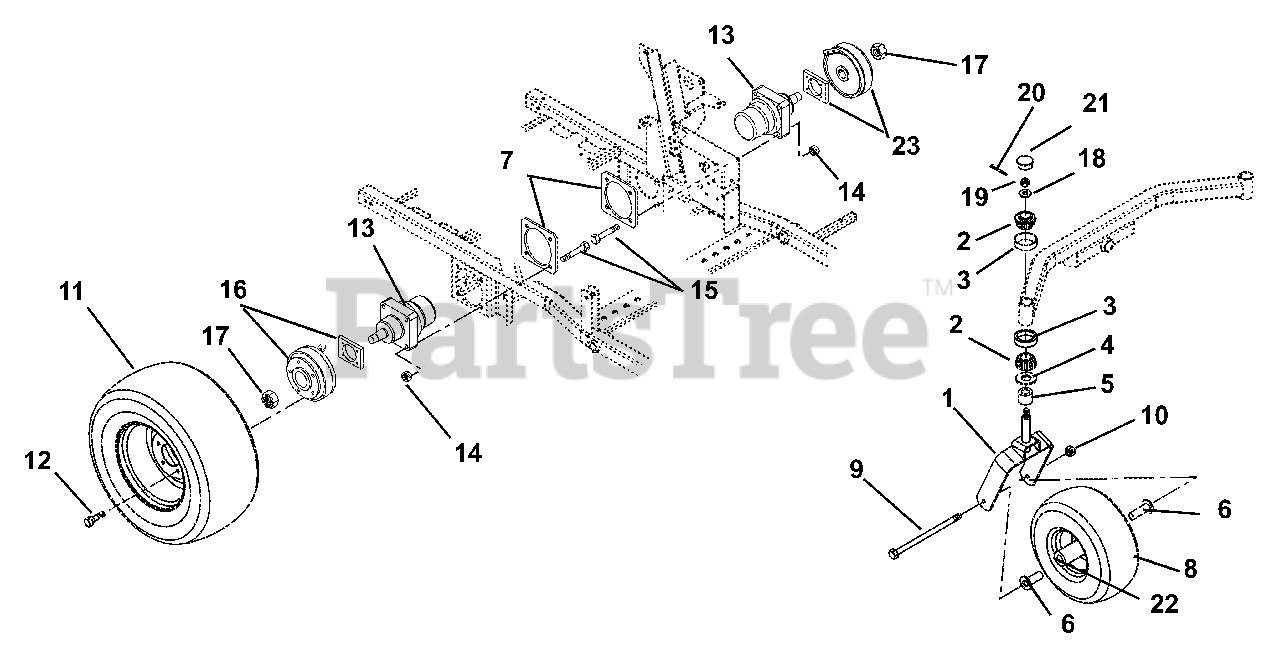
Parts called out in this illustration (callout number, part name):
1	FORK-FRONT
2	BRG, CONE W/ GREASE
3	BRG-CUP1.980X.420
4	BEARING SEAL 1.5 X 2 X .18
5	SPACER 1.005X1.5075X.375
6	SPACER - WHEEL
7	PLATE, MOTOR SUPPORT (BLACK)
8	WHEEL/TIRE ASM
9	@BLT-HEX .50-13X9.00 GR5 YWZC
10	@NUT-LK-CTR .50-13 YWZC
11	TIRE/WHEEL ASSY 24X12-12
12	BLT, LUG .50-20 X 1.38
13	MOTOR, PARKER WHEEL
14	@NUT-LK-TOP-FLG .50-13 YWZC
15	BOLT, WHEEL MOTOR 1/2-13X2.75
16	BRAKE, RH PARK (WOODS LH)
17	NUT-LK-JAM-PTCH 1.00-20
18	WSHR-FL-STL.755X1.375X.062YWZC
19	NUT, SLOTTED .75-16
20	@PIN-CTR .16X1.00 EXTPRSQCT YZ
21	CAP,DUST
22	BRG, 25MM ID X 52MM OD X 15MM
23	BRAKE, LH PARK (WOODS RH)
